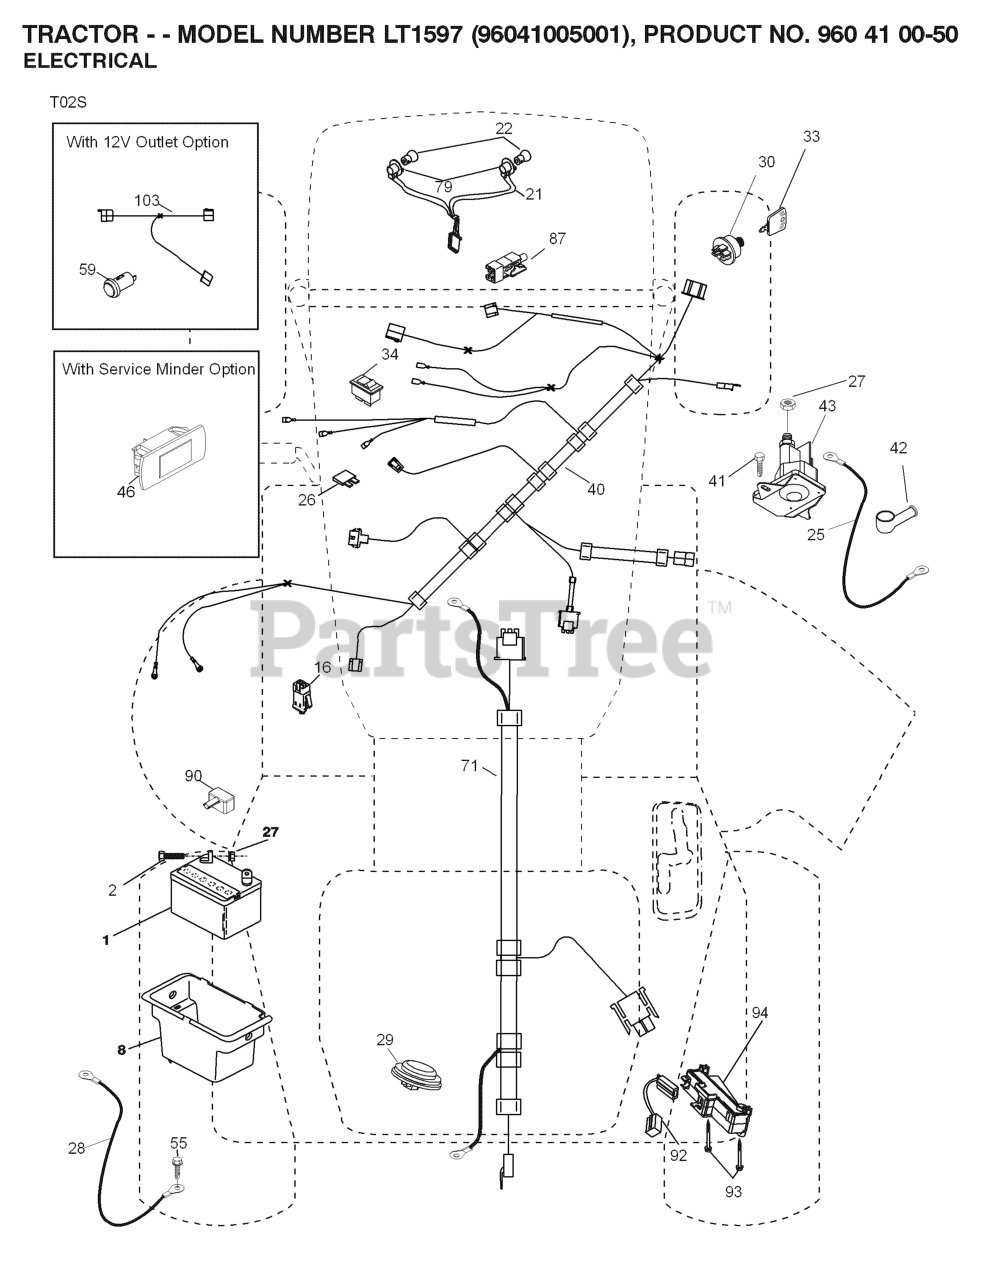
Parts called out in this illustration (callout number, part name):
1	DECK W/DECALS - RZ46
3	BLADE.MOWER.46".HI.LIFT
4	COVER.MANDREL.RH.46"
6	WHEEL.GAUGE.RALLY
7	BELT KEEPER 5"
8	PULLEY.IDLER.MWR.STATI.LH
9	PULLEY.IDLER.DECK
10	PULLEY.MANDREL.46"
11	SPRING.EXTENSION
12	SPRING, TORSION
14	COUPLING.QUICK CONNECT
15	PORT.WASHOUT
16	BAFFLE CENTER FRONT
17	BAFFLE FRONT RH
18	BRKT.DEFLECTOR.38"2005+
19	SHIELD.DEFLECTOR.MOWER.46"BLAC
20	MANDREL.W/SPCR.BRG.SHRT.NONRVL
21	IDLER BUSHING
22	BEARING.MANDREL.TOP.EXTENDED
23	SHAFT
24	ROD.HINGE
25	ARM.PNT.CLTCHG.STMP.46.RZ.EDIP
26	PLATE.PNT.REINF.DECK.46".EDIP
27	PLATE.REINFOR.46.SIDEBOLT.X431
28	EYE BOLT 5/16 X 3.50
29	STUD.FASTNER.W/ANTI-ROTATE
30	BOLT.SHOULDER.3/8-16X3-5/8.
31	SB 3/8-16 X 3/8 SKT HD ZD
32	SCREW.SEMS.7/16-20X1.HEX.HEAD
33	BOLT CARRIAGE
34	RP BOLT 5/16-18 X3/4 ZN/YEL GR
35	BOLT.HEX.7/16-14
36	BOLT.5/16-18X1-1/4 FULL THD
37	SCREW #10 X 1/2 SELF TAPPING
38	BOLT.HEX.WASHR.HED.313-18X1.19
39	SCREW.1/4-20X5/8
40	SCREW.BUTTONHEAD.1/4-20X1
41	NUT PUSH M
42	NUT 5/16C WHIZ
43	NUT HEX 3/8-16 NYLON, THIN
44	NUT.FLANGE.LOCK.TOP
45	NUT.LOCK.FLANGE.7/16
46	NUT LOCK FLG 3/8-16 UNC
47	5/16-18 NYLOC FLANGE NUT
48	NUT.71038.31-18.HEX.NYLOCK
49	NUT T
50	WASHER
51	WASHER 5/16 FLAT
52	WASHER 3/8 X 3/4 X .187 TK
53	WASHER 7/16 FLAT ZD
